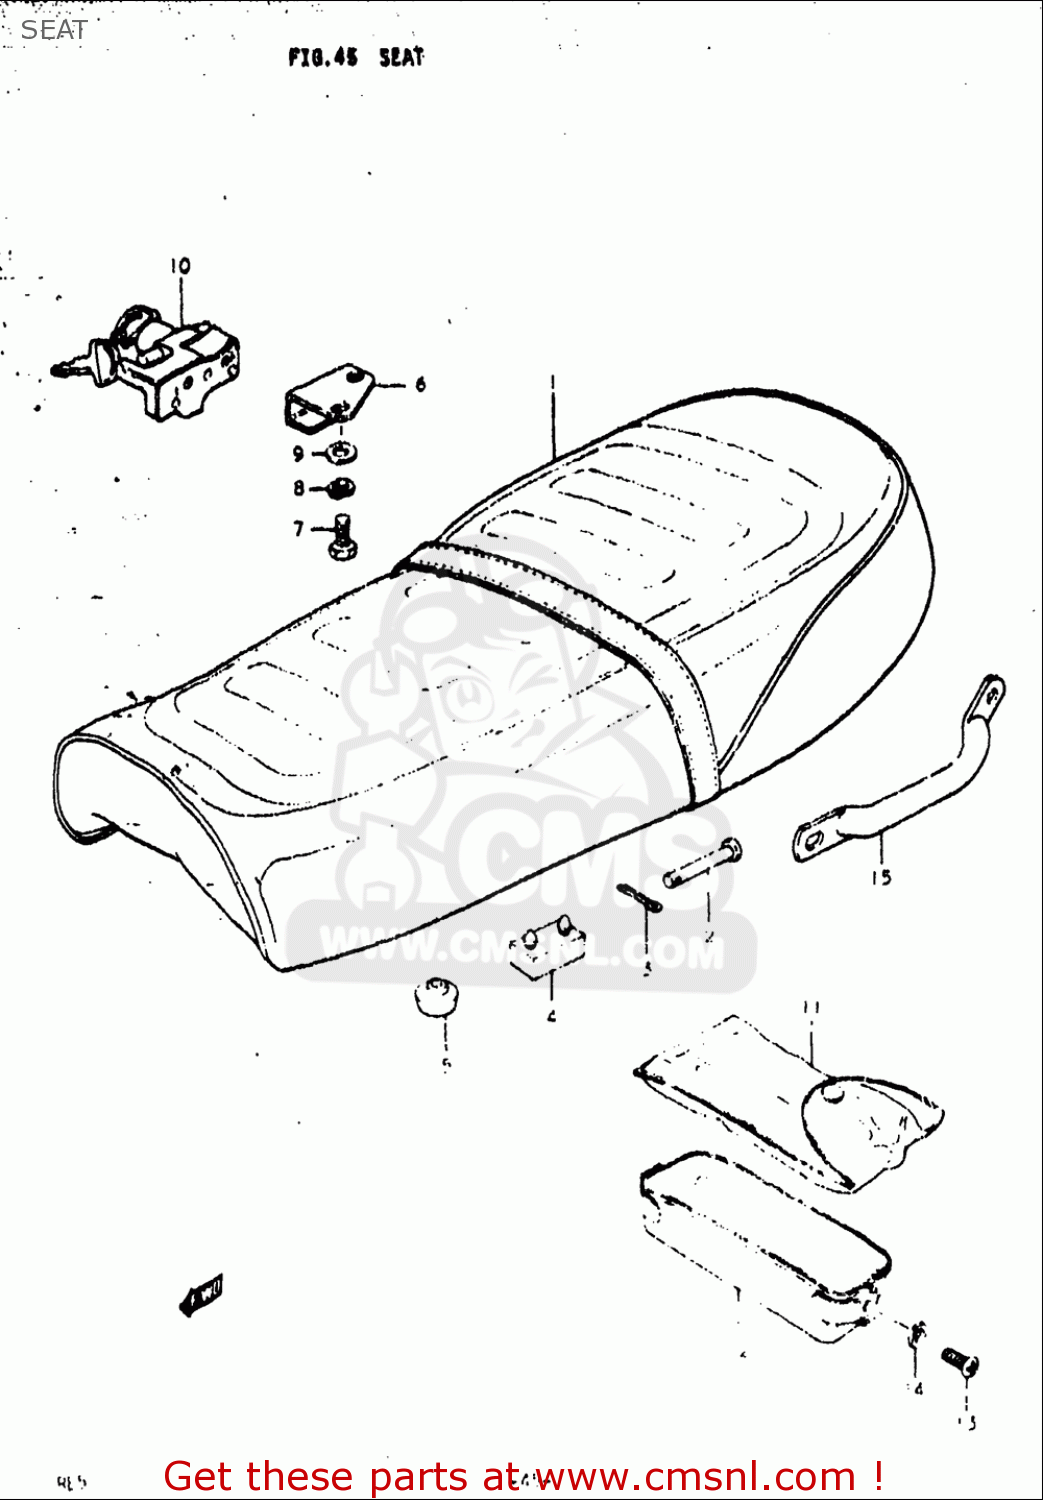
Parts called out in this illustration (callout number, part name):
2	PIN
3	PIN
4	CUSHION
5	CUSHION
6	PLATE,SEAT CLAMP GUIDE
7	BOLT
8	WASHER,LOCK
9	WASHER
13	SCREW
14	WASHER,LOCK
15	GRIP,FRAME HANDLE
